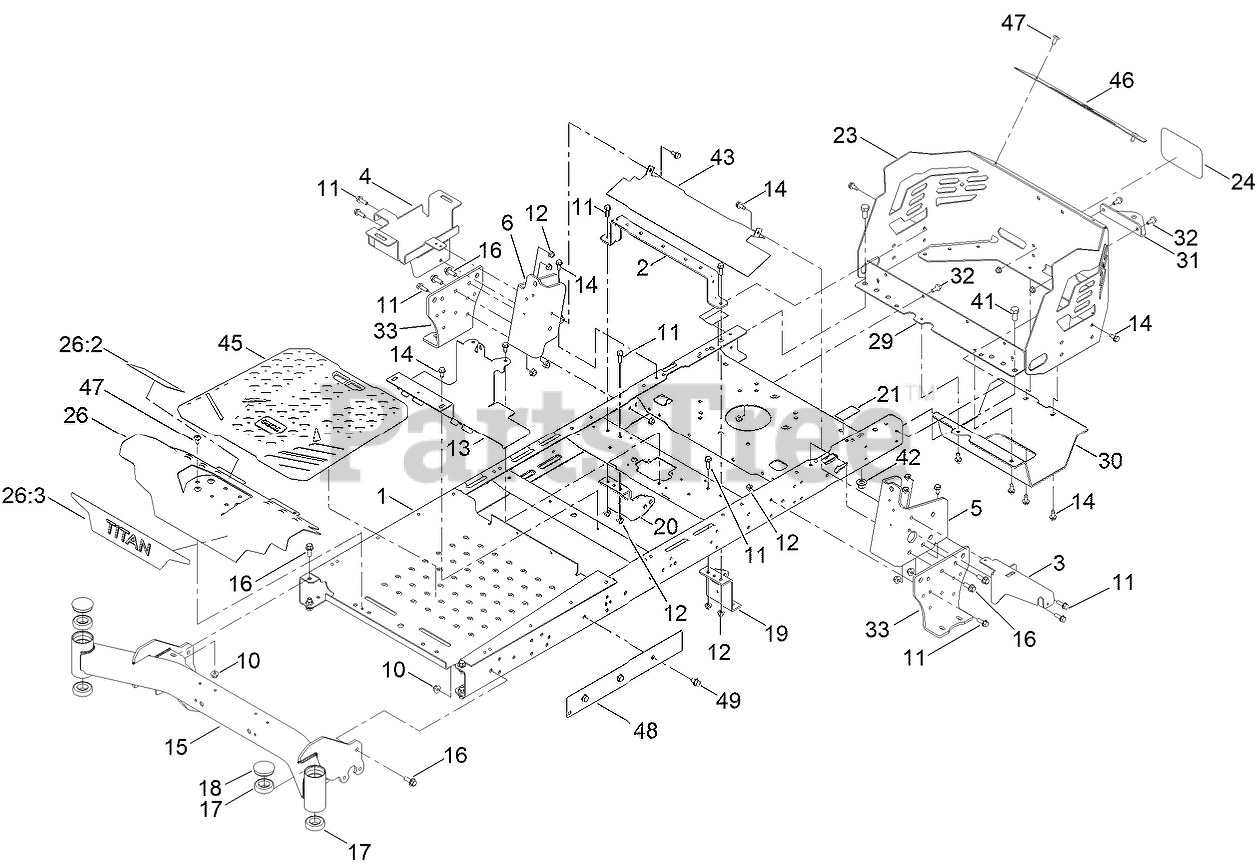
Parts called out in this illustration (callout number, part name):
1	FRAME ASM
2	BRACE-SEAT, REAR (WIDE)
3	BRACKET-SUPPORT, POD (LH)
4	TRAY-BATTERY
5	BRACKET-MOUNTING, LH
6	BRACKET-MOUNTING, RH
10	NUT-HF, NI
11	SCREW-HHF
12	NUT-HF, NI
13	BRACKET-MOUNT
14	SCREW-HWHTF
15	FRONT AXLE ASM
16	SCREW-HHF
17	BEARING-BALL
18	CAP-GREASE
19	MOUNT-HYDRO, FRONT (LEFT)
20	MOUNT-HYDRO, FRONT (RIGHT)
21	DECAL-BYPASS
23	GUARD-ENGINE
24	DECAL
26	FOOTREST-TITAN
26:2	DECAL-DANGER
26:3	DECAL-TITAN
27	DECAL-TITAN
29	CROSSMEMBER-REAR, WIDE
30	GUARD-MUFFLER
31	BRACKET-HITCH
32	SCREW-HHF
33	MOUNT-HYDRO
41	SCREW-HH
42	NUT-LOCK
45	FLOOR MAT
46	TRIM-GUARD, ENGINE
48	PLATE-FRAME
49	SCREW-HWHTF
